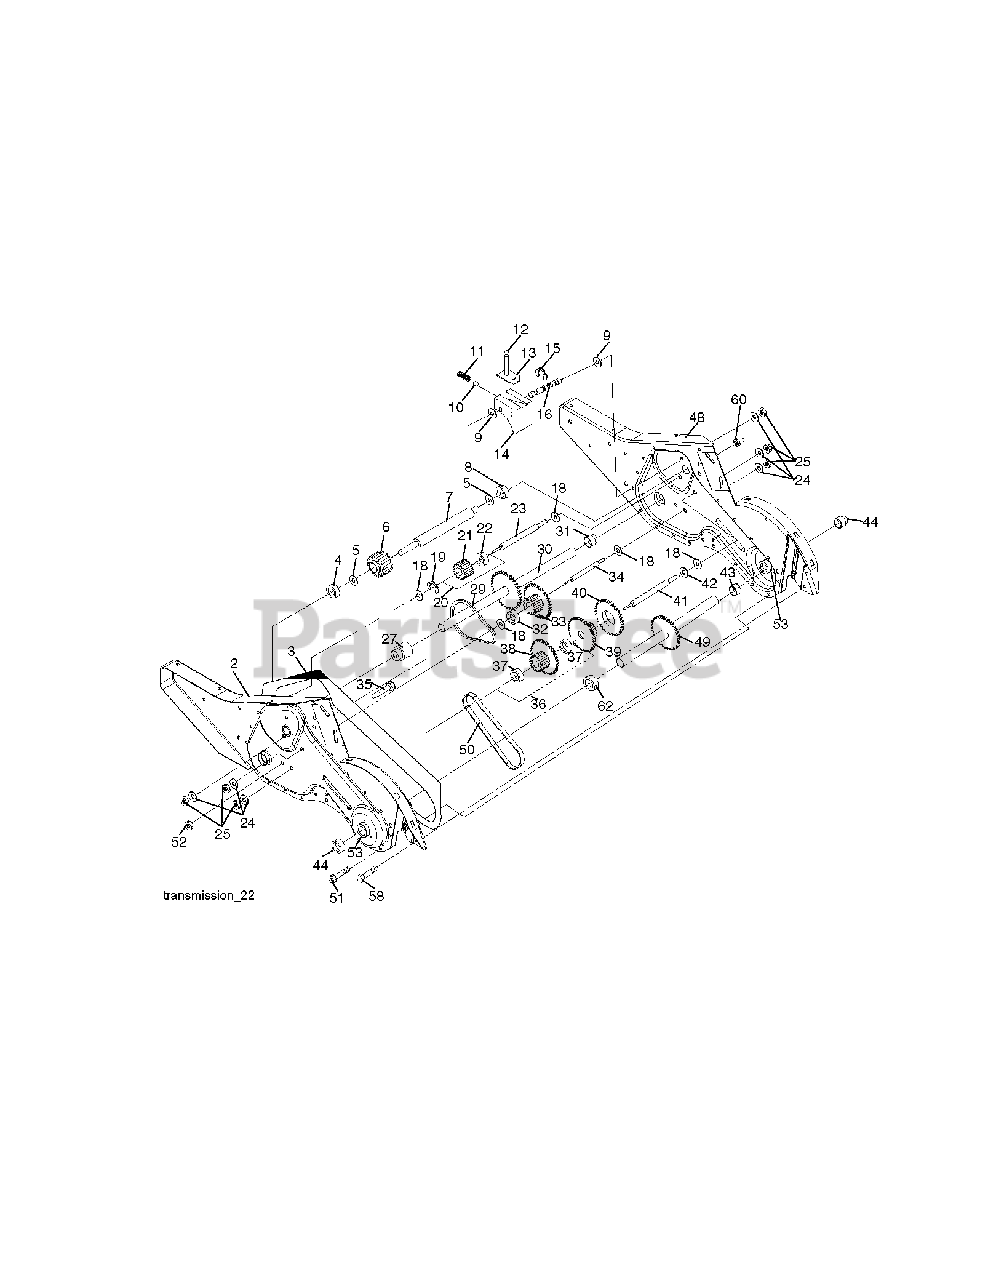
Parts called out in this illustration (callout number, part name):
2	GEARCASE.ASM.CRT.LH.W/BEARING
3	GASKET.GEARCASE.CRT/DRT.TILLER
4	NEEDLE BRNG LT
5	THRUST WASHER
6	GEAR.PINION.INPUT
7	SHAFT.INPUT."D".TILLER
8	BEARING TI
9	WASHER, SEAL (2 2)
10	STEEL BALL KIT
11	SPRING-SHIFT CRT
13	BRACKET ASM.SHIFT.CRT
14	SHIFT FORK TI
16	SHAFT.SHIFTER.TILLER
20	GEAR ASSY CRT
21	GEAR-REV IDLR CRT
22	NEEDLE BEARING TI
24	LOCKWASHER
25	NUT.ASF.HEX.7/16
27	BEARING.GROUND.DRIVE
30	GROUND SHAFT ASS'Y
31	BEARING, SHAFT RH CRT
33	SPRCKT 8 GEAR CRT
34	SHAFT.SECONDARY.REDUCTION.CRT
35	SCRW WHIZ LOK CRT
36	SPROCKET.ASM.W/BEARING.TILLER
37	BEARING
38	SPROCKET, TINE
41	SHAFT.REDUCTION.TILLER
42	BRNG RACE T
44	SEAL ASM, OIL
48	GEARCASE.ASM.CRT.RH.W/BEARING
49	SHAFT.ASM.TINE
50	CHAIN.TILLER
51	SCREW
53	BEARING KIT
58	BOLT SHOULDER 1/4-20 UNC X.875
60	FITTING.GREASE.TAPERED
62	SPACER.1.015X1.50X.650
